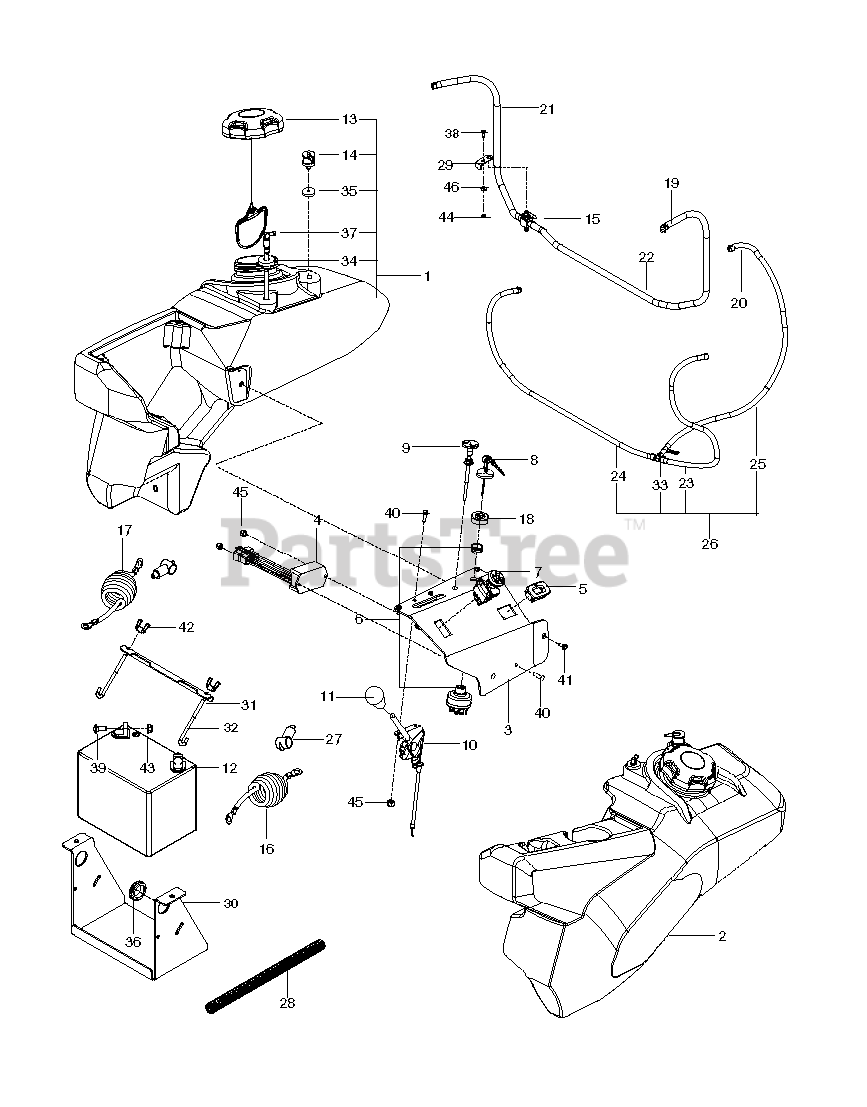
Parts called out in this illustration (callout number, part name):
1	RT FUEL TANK ASM EPA
2	LT FUEL TANK ASM EPA
3	PANEL.CONTROL.GAS.GRAY
4	TIMER, SEAT
5	HOUR METER
6	SWITCH, IGNITION, INDAK
7	SWITCH, PTO 10 AMP
8	KEY, IGNITION
9	CABLE, CHOKE, 48"
10	CABLE, THROTTLE, 46"
11	KNOB - SHIFT
12	BATTERY, 12 V 330 AMP
13	CAP, FUEL
14	VALVE.FUEL.CHECK
15	FUEL VALVE
16	CABLE, POSITIVE, 55"
17	CABLE, NEG, 55"
18	CAP IGNITION NUT
19	HOSE CLAMP
20	CLAMP, HOSE
21	LINE, FUEL, 22"
22	LINE, FUEL, 38"
23	HOSE, 3/16" VAPOR, 21"
24	HOSE, VAPOR 3/16 X 39"
25	HOSE, VAPOR 3/16 X 30"
26	ASSEMBLY, VAPOR LINE
28	LOOM, SPLIT, CONVOLUTED
29	BRACKET,FUEL VALVE, BLACK
30	BRACKET, BATTERY, BLK
31	BRACKET, BATTERY MOUNT
32	HOOK, "J"
33	TEE, FUEL LINE 3/16"
34	RUBBER GROMMET
35	GROMMET, CHECK VALVE
36	RUBBER GROMMET
37	FITTING, FUEL
38	HCS 1/4C X 3/4 HCS
39	BOLT 5/16C X 3/4" CARRIAGE
40	SCR #10-24 X .75 SKT HD BLK
41	SCR #10-24 X 3/8 SKT HD BLK OX
42	WING NUT 1/4
43	5/16-18 NYLOC FLANGE NUT
44	JAM NUT 1/4C (2 2 PW01)
45	NUT 10-24 NYLOC
46	WASHER 1/4 FLAT
